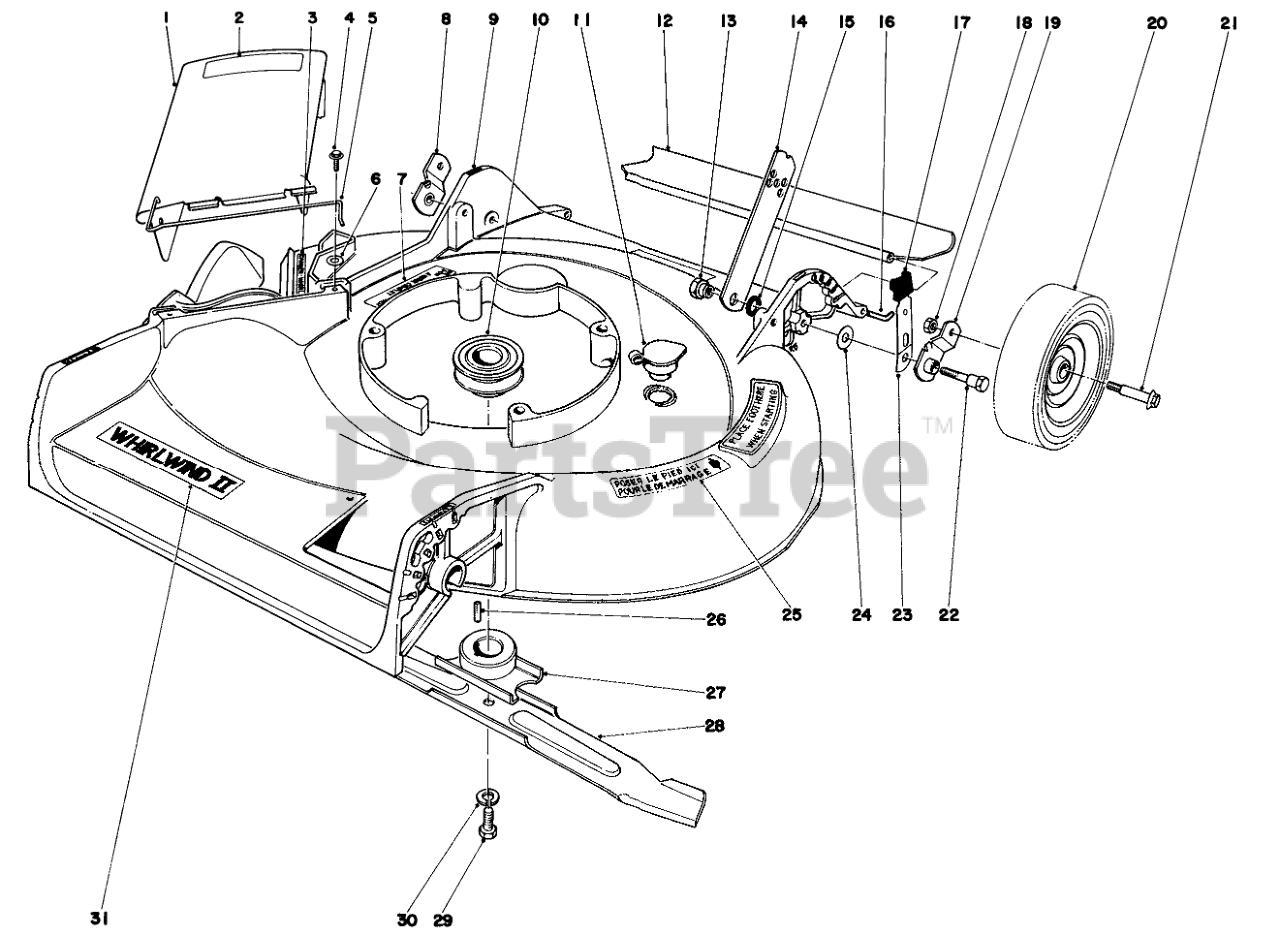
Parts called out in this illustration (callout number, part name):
1	Deflector Cover Assembly (Incl. Ref. #2 & 5)
2	Decal-Caution
3	Decal-Danger
4	SCREW
5	SPRING HINGE
6	WASHER-FLAT
7	Decal-Warning
8	Pivot Arm
9	Housing
10	DRIVER PULLEY
11	WASHOUT PLUG
12	REAR SAFETY SHIELD 21
13	HANDLE PIVOT NUT
14	HANDLE LATCH
15	HANDLE LATCH SPACER
16	SHIELD ROD
17	KNOB-ARM
18	Nut
19	Pivot Arm
20	Wheel Assembly
22	PIVOT SCREW
23	SPRING ARM ASM
24	WASHER-PIVOT
25	Decal-Step
26	KEY-SQUARE
27	Blade Retailer
28	Blade
29	SPECIAL SCREW
30	WASHER-LOCK
31	Decal Whirlwind
